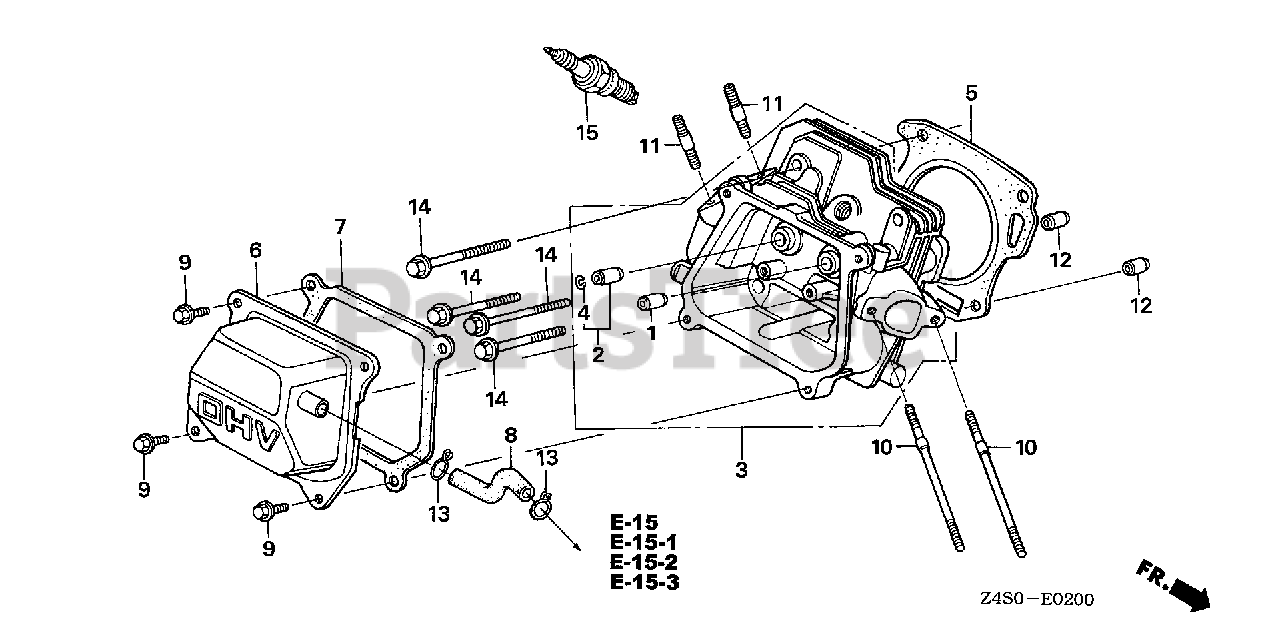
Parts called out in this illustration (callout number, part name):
1	GUIDE, VALVE (OVER SIZE) Use from Engine SN 6324986.
2	GUIDE, EX. VALVE (OS)
3	CYLINDER HEAD
4	CLIP, VALVE GUIDE Use from Engine SN 1231803.
5	GASKET, CYLINDER HEAD (NIPPON LEAKLESS)
6	COVER, HEAD
7	GASKET, CYLINDER HEAD COVER
8	TUBE, BREATHER
9	BOLT, FLANGE (6X12) (CT200)
10	BOLT, STUD (6X109)
11	BOLT, STUD (8X32)
12	PIN A, DOWEL (10X16)
14	BOLT, FLANGE (8X60)
15	SPARK PLUG (BPR5ES) (NGK)
15	SPARK PLUG (W16EPR-U) (DENSO)
15	SPARK PLUG (BPR6ES) (NGK)
15	SPARK PLUG (W20EPR-U) (DENSO)
